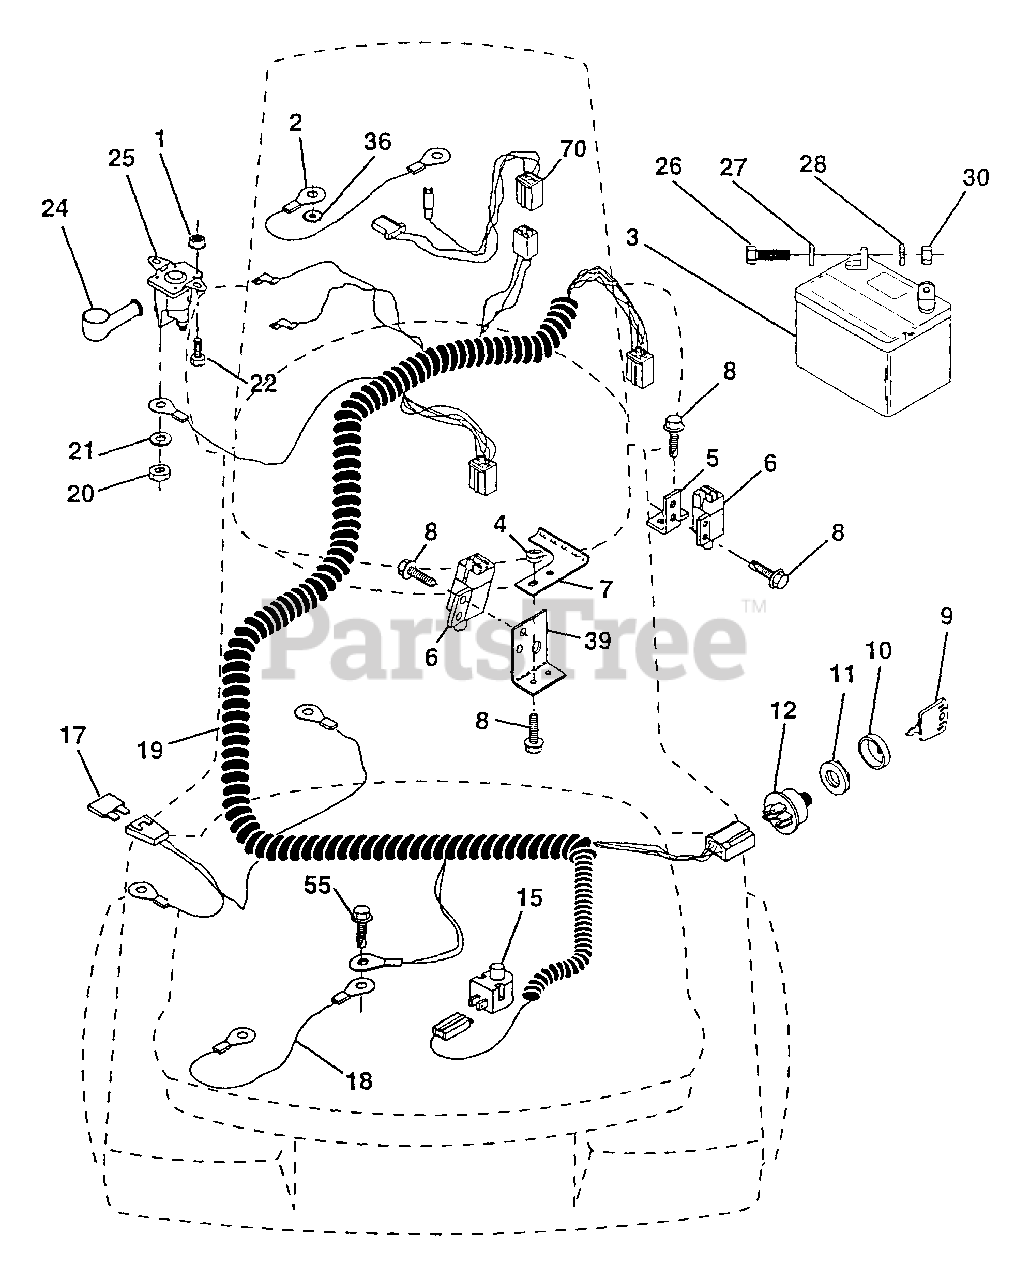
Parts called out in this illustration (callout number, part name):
1	Nut, Hex Keps 1/4-20
2	Assembly, Cable
3	Battery (AYP part number)
4	Nut Lock #10-24 UNC
5	Bracket, Switch
6	Switch, Interlock (4-terminal)
7	Keeper Actuator
8	Screw, Hex Hd. Tap #10-24 x 1/2
9	Key, Steel Delta
10	Cover, Key Ignition
11	Nut, Ignition (AYP part number)
12	Switch, Ignition (AYP part number)
15	Switch, Plunger
17	Fuse
18	Assembly, Cable
19	Harness, Ignition
20	Nut, Hex Jam 1/4-20
21	Washer, Lock 1/4 (AYP part number)
22	Bolt, Fin. Hex 1/4-20 UNC x 1/2 Gr. 5
24	Cover, Terminal
25	Solenoid
26	Bolt, Hex Hd. 1/4-20 UNC x 3/4
27	Washer 9/32 x 5/8 x 16
28	Washer, Lock 1/4
30	Nut, Fin. Hex 1/4-20 UNC
36	Washer Lock Inter. Tooth 1/4
39	Bracket Switch Clutch
55	Screw, Thdrol. 5/16-18 x 1/2
70	Harness Engine (AYP part number)
